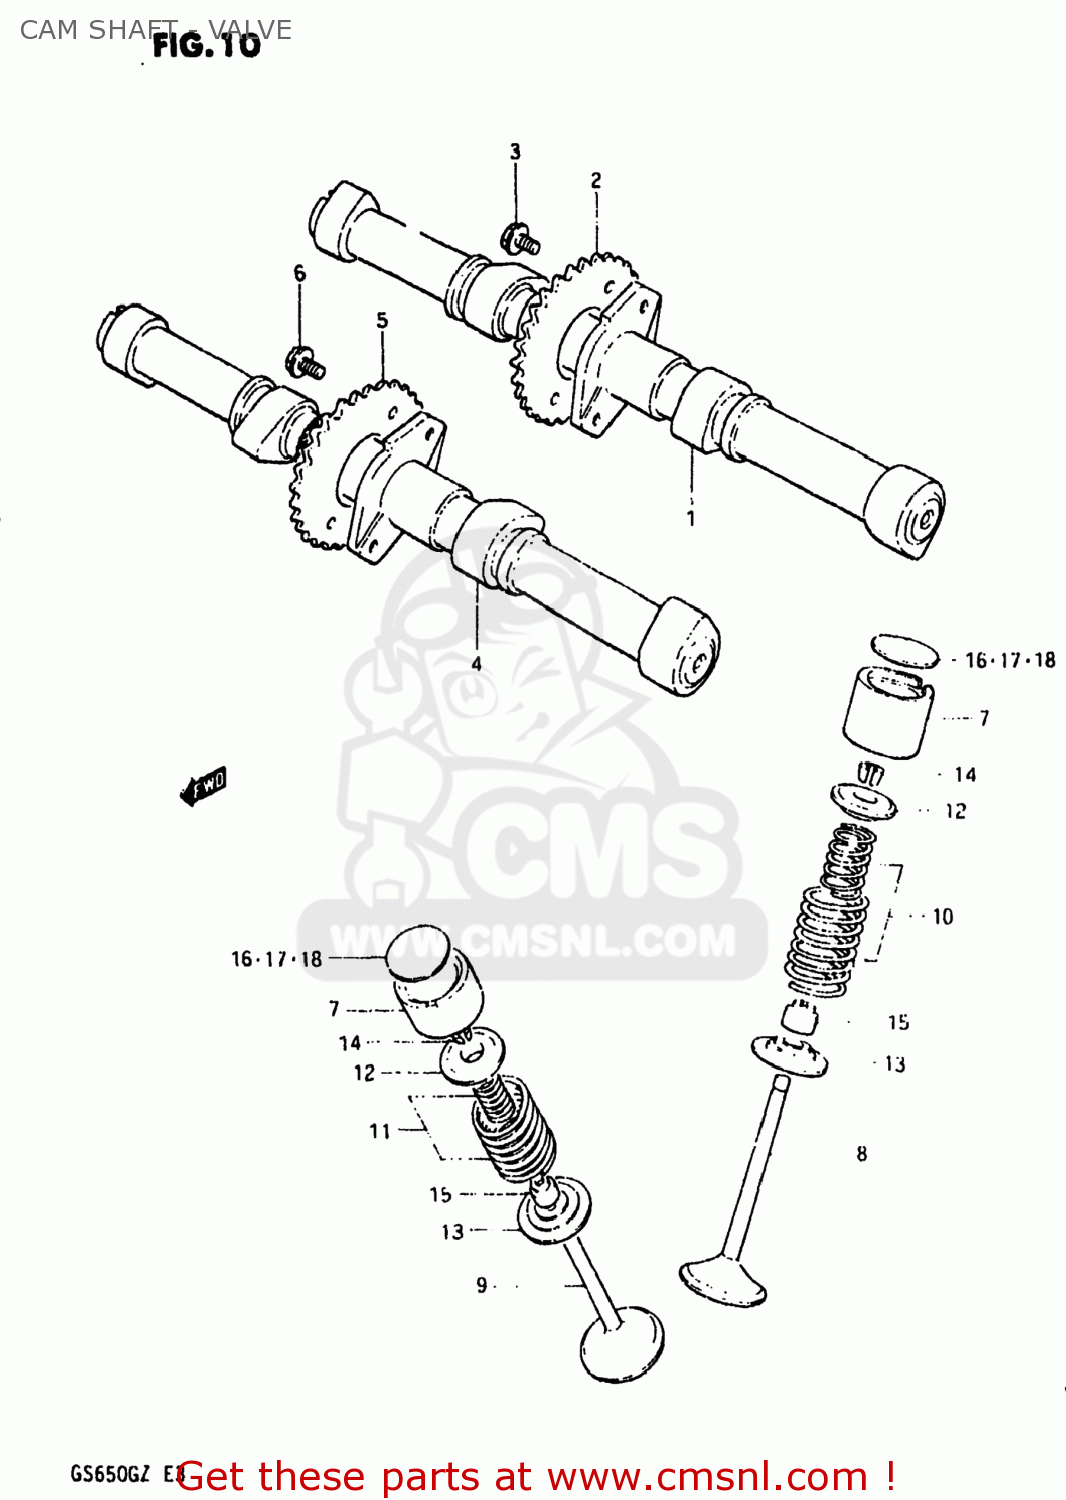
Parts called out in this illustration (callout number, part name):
1	CAMSHAFT,INTAKE
2	SPROCKET,INTAKE CAMSHAFT
3	BOLT(7X11)
4	CAMSHAFT,EXHAUST
5	SPROCKET,EXHAUST CAMSHAFT
6	BOLT(7X11)
7	TAPPET
8	VALVE,INTAKE
9	VALVE,EXHAUST
10	SHIM,TAPPET
11	SHIM,TAPPET
12	RETAINER,VALVE SPRING
13	SEAT,VALVE SPRING
14	COTTER VALVE
15	SEAL,OIL(7X14.4X9)
16	SHIM,TAPPET
17	SHIM,TAPPET
19	SHIM SET,TAPPET
20	CASE
